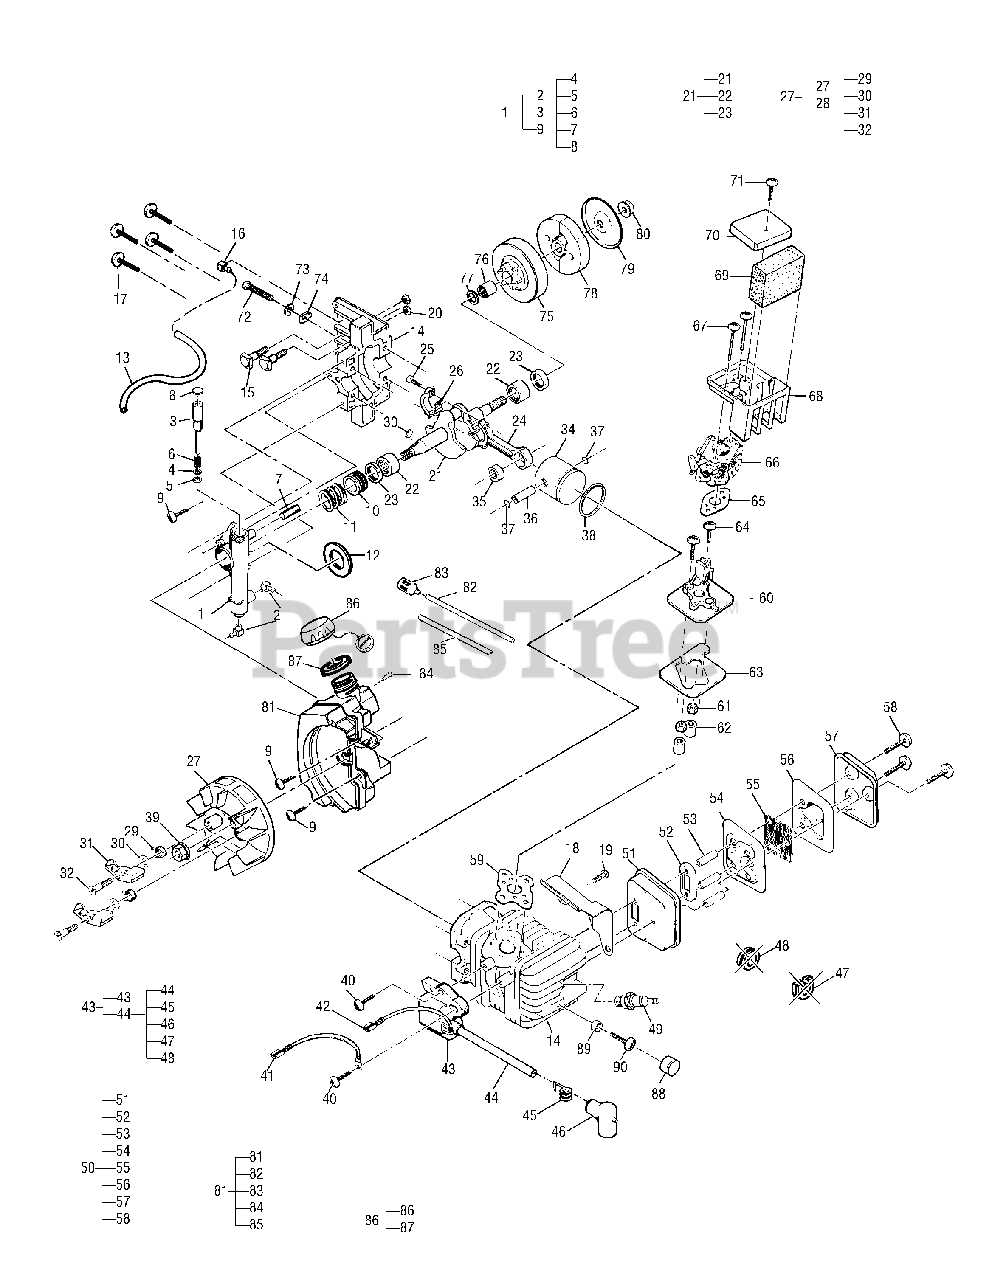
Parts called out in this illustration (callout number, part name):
1	Oil Pump Asy
3	Kit, Gear/Plunger Asy
4	Washer
5	O-Ring
6	Spring
7	Pin, Dowel
8	Plug, Oil Pump
9	Screw, 10-24 x .62 Tr Hd Torx
10	Worm Gear
11	Spring, Compression
12	Seal, Foam, Oil Pump
13	Connecting Hose
14	Short Block Asy
15	Bolt, Bar
16	Fitting
17	Screw, 12-24 x 1.0 Hx Wshr Hd
18	Baffle, Air
19	Screw, 10-24x.625
20	Nut, Hx 1/4-28 Flange
21	Crankshaft/Bearing Asy
22	Bearing, C'shaft
23	Seal, C'shaft Oil
24	Connecting Rod/Bearing
25	Screw, Conn Rod
26	Set, Roller Pins
27	Flywheel/Pawl Asy
28	Kit, Flywheel Pawls
29	Spring, Starter Pawl
30	Washer, Sp .469 OD x .222 ID
31	Pawls
32	Pin, Starter Pawl
33	Key, Flywheel
34	Piston
35	Bearing, Needle-Drawn Cup
36	Pin, Piston
37	Ring, Snap
38	Piston, Ring
39	Nut, Hx 5/16-24
40	Screw, Tr 10-24 x .75 Torx
41	Wire Asy, Ground
42	Wire Asy, Stop Switch
43	Ignition Asy
44	Kit, Plug Wire
45	Connector
47	Grommet
48	Grommet
49	Spark Plug RDJ7Y
50	Muffler Asy
51	Body
52	Plate, Reinforcing
53	Spacer
54	Baffle, Inner Muffler
55	Screen, Spark Arrester
56	Baffle, Outer
57	Cover, Muffler
58	Screw, 10-24 x 1.75 Tr Hd Torx
59	Gasket, Insulator
60	Insulator, Carburetor
61	Nut, Hx 10-24
62	Spacer, Rubber
63	Seal, Foam
64	Screw, Tr 10-24 x 1.00 Torx
65	Gasket, Carburetor
66	Carburetor/Choke Asy
67	Screw, Tr 10-24 x 2.0 Torx
68	Box, Air Filter
69	Filter, Air
70	Shield, Carburetor
71	Screw, 10-14 x .625 Plastite
72	Gas Bar Adj Screw Nut & Ring
73	Ring, Retaining
74	Nut, Bar Adjusting
75	Drum/Sprocket/Bearing Asy
76	Bearing
77	Washer, Sprocket
78	Kit, Clutch Asy
79	Plate, Dust
80	Nut, Clutch, 5/16-24 LH
81	Fuel Tank Asy
82	Hose, Fuel Pickup
83	Filter, Fuel
84	Valve, Duckbill
85	Hose, Primer Retain
86	Cap, Fuel Asy
87	Gasket, Fuel Cap
88	Cover Cylinder
89	Cover, Spacer
90	Screw, 10-24x.75 Tr Torx
